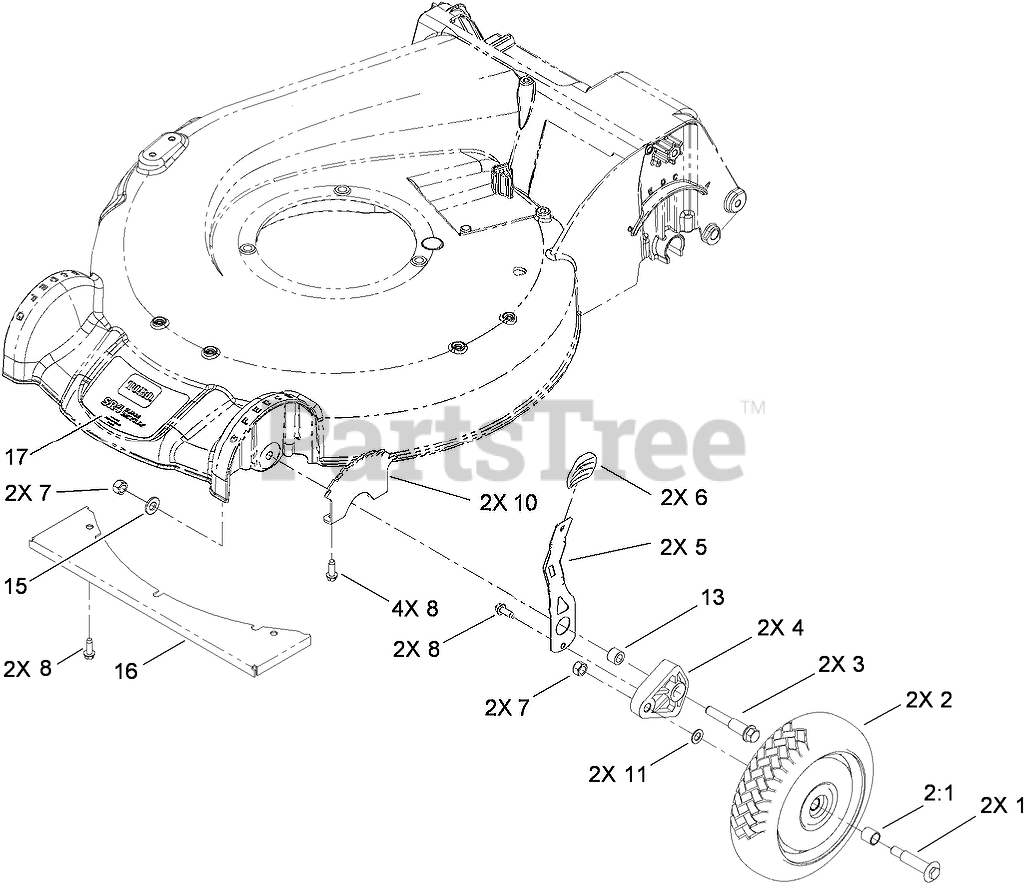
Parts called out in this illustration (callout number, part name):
1	BOLT-SHOULDER
2	WHEEL AND TIRE ASM
2:1	BUSHING
3	SCREW-SHOULDER
4	ARM-PIVOT
5	ARM-SPRING
6	Knob-Lever, HOC
8	SCREW-HWHTF
10	PLATE-HOC
11	WASHER
13	SPACER-WHEEL
15	WASHER-FLAT
16	PLATE-COVER, FRONT
17	DECAL-HOUSING
